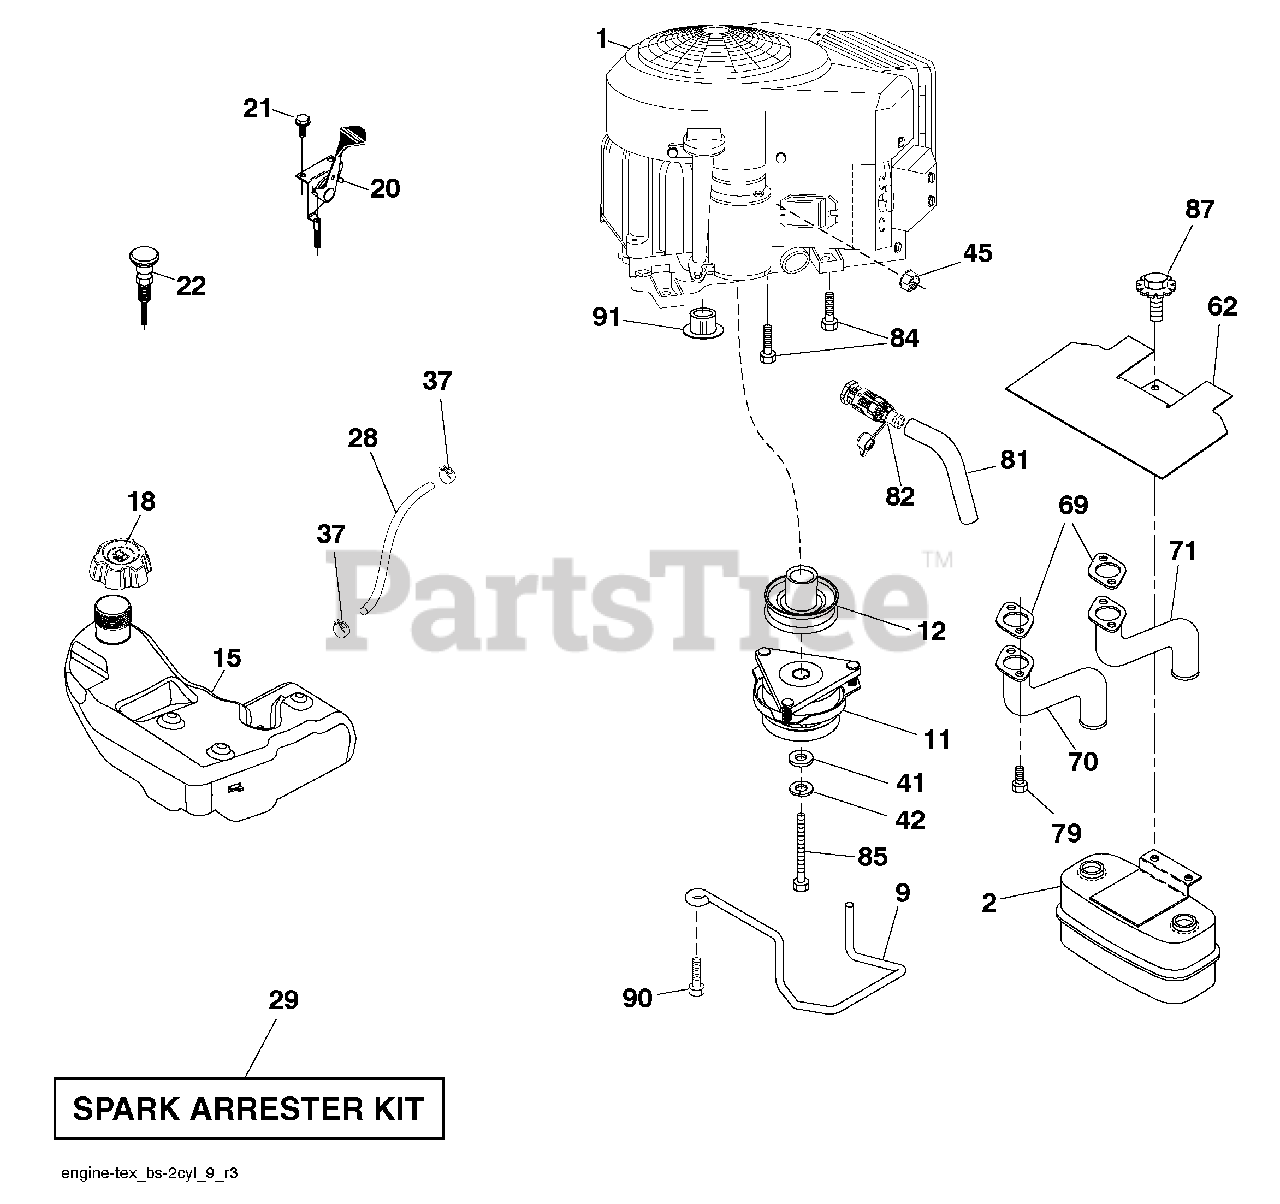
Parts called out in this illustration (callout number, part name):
2	Muffler
9	Keeper Belt Engine
11	Clutch Electric
12	Pulley Engine
15	Tank Fuel 4.0
18	Cap Asm Fuel
20	Control Throttle
21	Screw #10 x .750 BOS Thread
22	Control Choke
28	Fuel Line
29	Spark Arrester Kit
37	Clamp Hose
41	Washer 1-1/2 OD x 15/32 ID x .250
42	Washer Lock 7/16
45	Nut Keps Hex 1/4-20 unc
62	Shield Heat Muffler
69	Gasket
70	Tube Exhaust LH
71	Tube Exhaust RH
79	Screw Socket Head
81	Tube Drain Oil Easy
82	Valve Drain Oil
84	Screw 3/8-16 x 1-1/4
85	Bolt Hex 7/16-20 x 3.75 Gr. 5
87	Bolt 5/16-18 unc x 1 w/Sems
90	Screw 3/8-16 x 1
91	Bushing 1.375 OD
